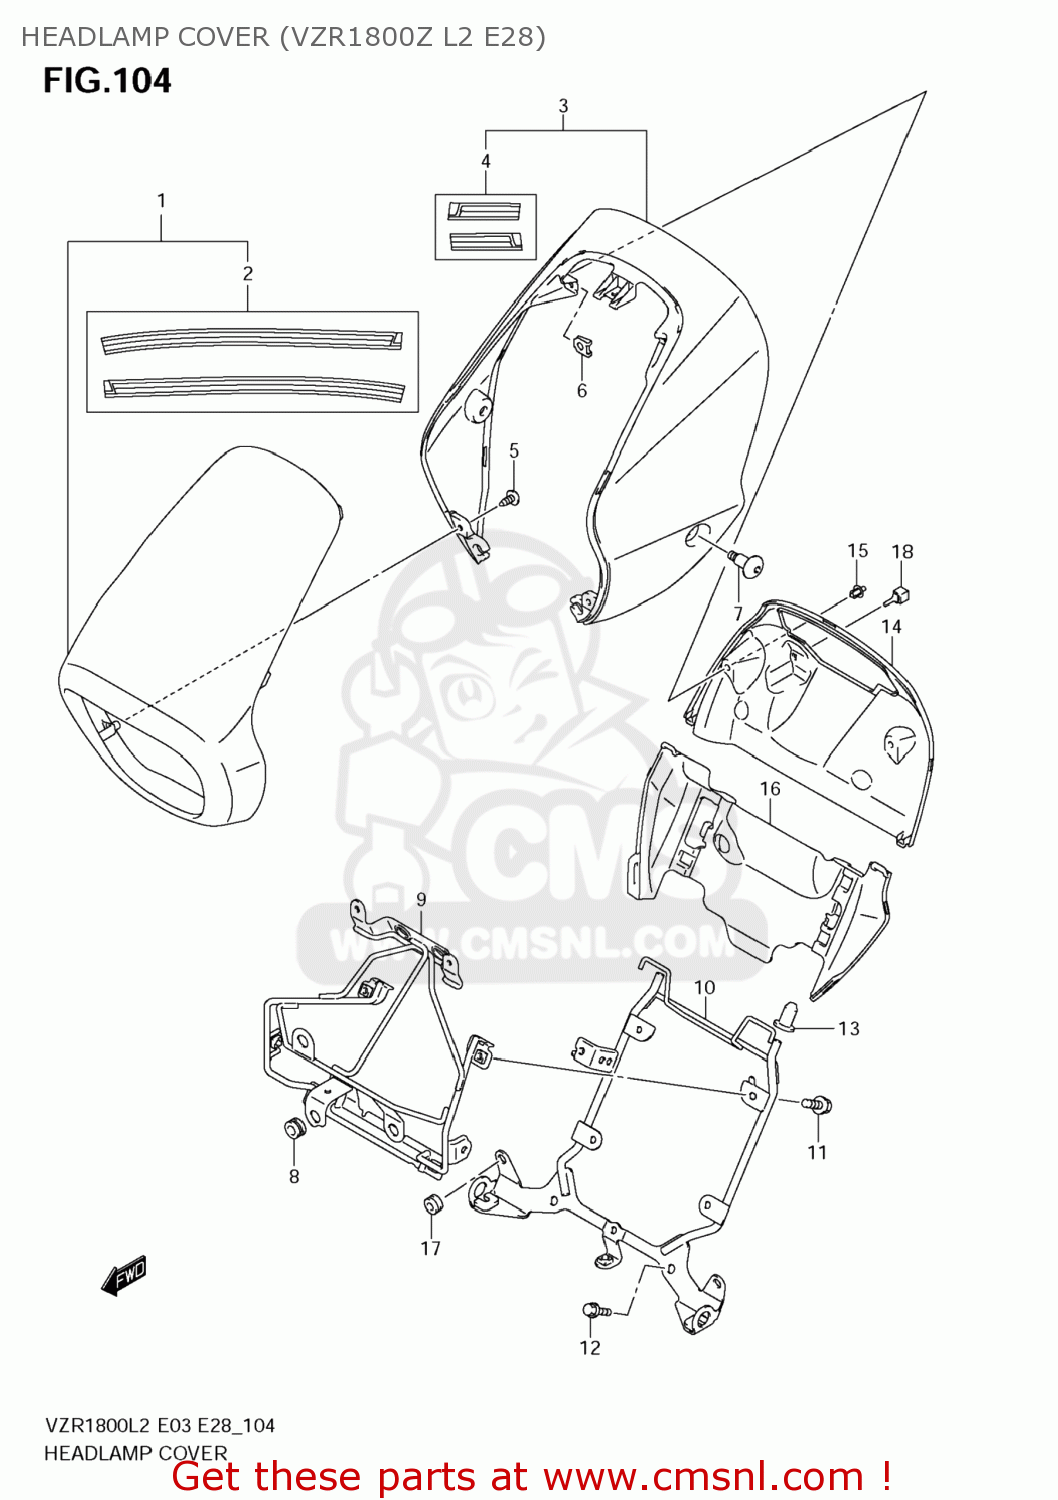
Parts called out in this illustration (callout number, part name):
1	COVER,HEADLAMP
2	TAPE SET,HEADLAMP HOUSING
3	COVER,HEADLAMP LWR
4	TAPE SET,HEADLAMP HOUSING LWR
5	SCREW
6	NUT
7	SCREW(6X22)
8	CUSHION
9	BRACE,HEADLAMP HOUSING
10	BRACE COMP,HEA
11	BOLT
12	BOLT
13	CUSHION,HEADLAMP HOUSING BRACE
14	COVER,HEADLAMP UPR
15	CLIP(BLACK)
16	COVER,HEADLAMP HSG BRACKET
17	CUSHION
18	CUSHION,HEADLAMP COVER UPR
